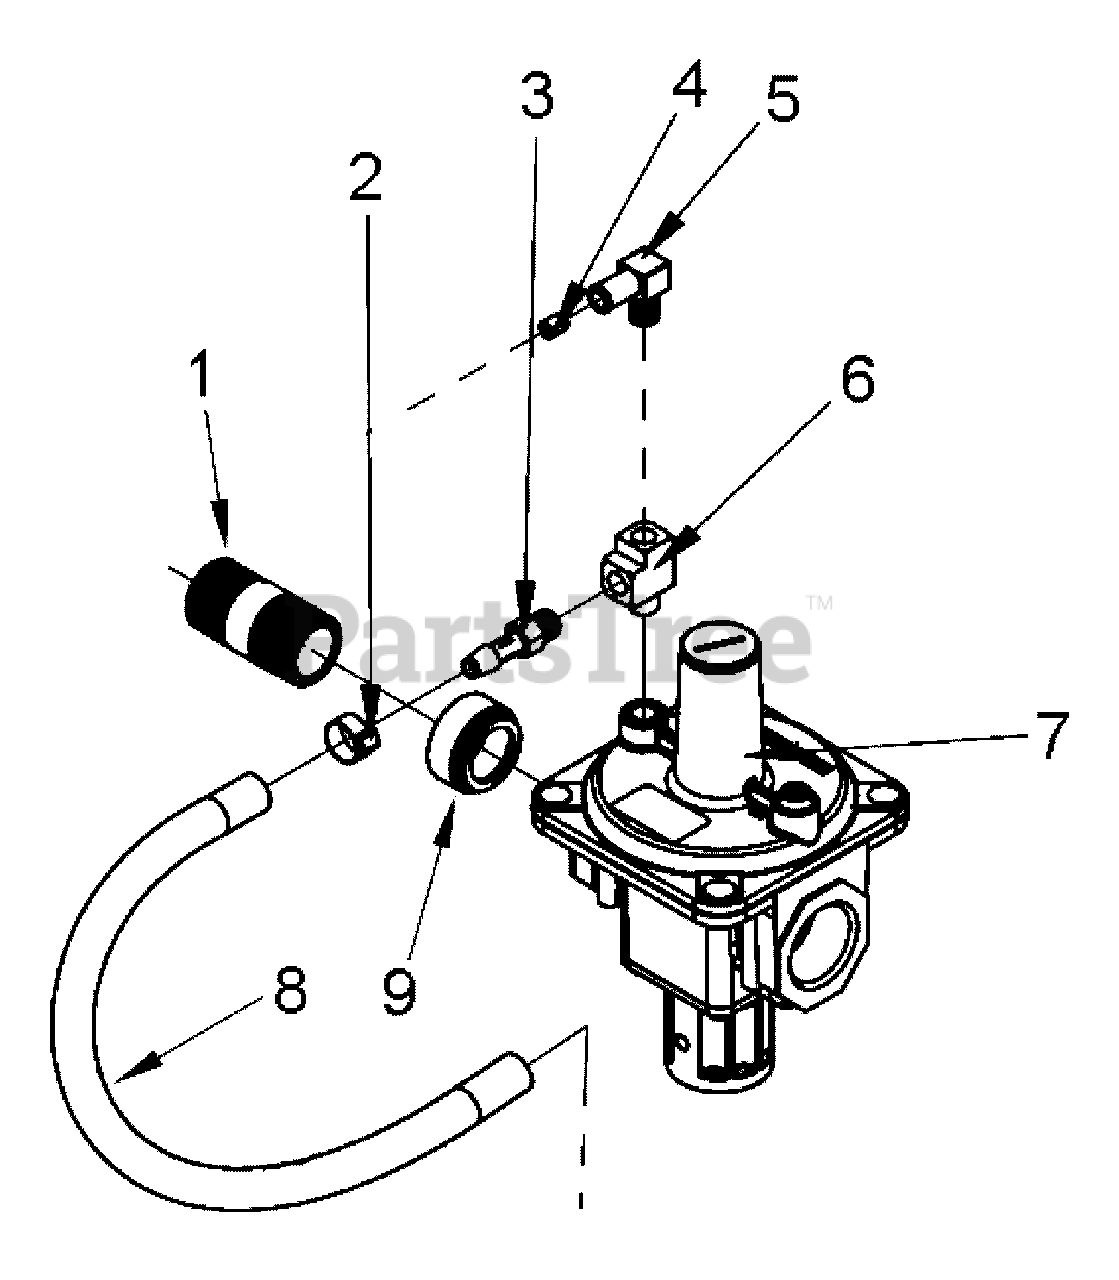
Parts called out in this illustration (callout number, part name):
1	PIPE
2	CLAMP
3	FITTING
4	JET
7	REGULATOR-FUEL
8	HOSE
9	BUSHING
